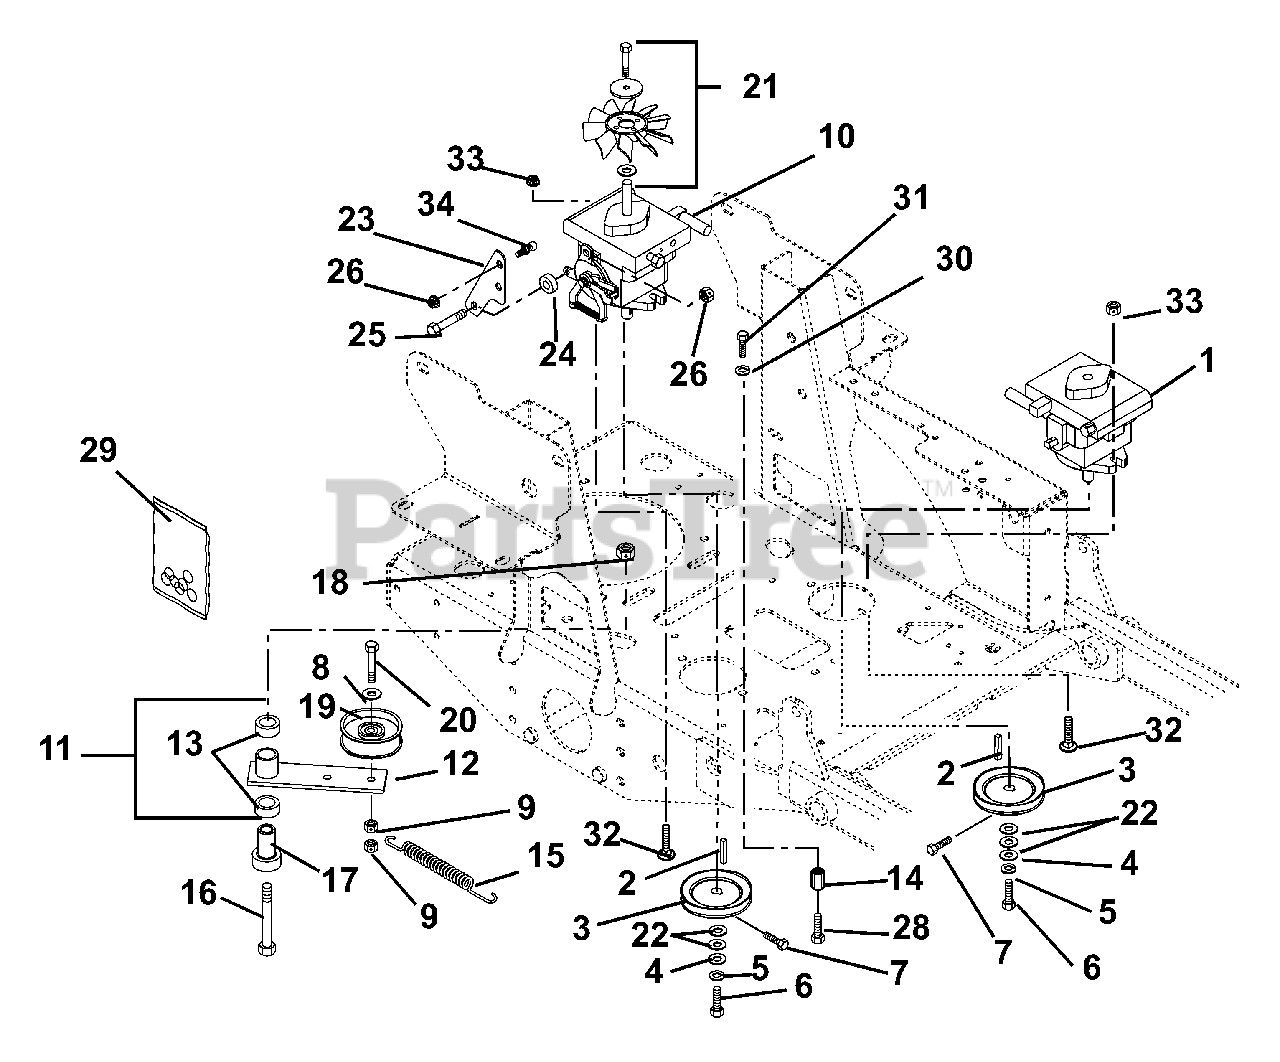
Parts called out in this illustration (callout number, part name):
1	Pump, Hydraulic BDP-10A Left Hand
2	Key, Straight 5mm x 25mm x 5mm
3	Sheave 4.0 x .199
4	Washer, Flat Steel .281 x 1.00 x .063
5	Washer, Locking .25 x .062
6	Bolt, Hex M6 x 1.00 x 12
7	Bolt, Hex .25-20 x .50 Grade 5
8	Washer, Flat Steel .39 x .75 x .125
9	Nut, Nyloc Flange 3/8-16
10	Pump, Hydraulic BDP-10A Right Hand
11	Assembly, Idler Arm Guard Drive
12	Weldment, Idler Arm Ground Drive
13	Bearing, 1.00 x 1.12 x .75
14	Nut, Coupling .375-16 x 1.75
15	Spring, Tension .120 x .845 x 6.50
16	Bolt, Hex .50-13 x 3.50 Grade 5
17	Bearing, Pedestal
18	Nut, Nyloc Flange .50-13
19	Idler, Flat 4.00 x 1.06
20	Bolt, Hex .38-16 x 2.25 Grade 5
21	Fan, Cooling
22	Washer, Flat Steel .656 x 1.31 x .095
23	Bracket, Return to Neutral/Damper
24	Spacer .344 x 1.00 x .375
25	Bolt, Hex .31-18 x 1.25 Grade 5
26	Nut, Nyloc Flange 5/16-18
27	Washer, Flat Steel .344 x .688 x .065
28	Bolt, Hex .38-16 x 1.50 Grade 5
29	Kit, Pump Seal (BDP-10A)
30	Washer, Locking .38 x .094
31	Bolt, Hex .38-16 x .75 Grade 5
32	Bolt-Round Head Square Neck .44-14 x 1.50 Grade 5
33	Nut, Nyloc Flange .44-14
34	Stud, Ball
